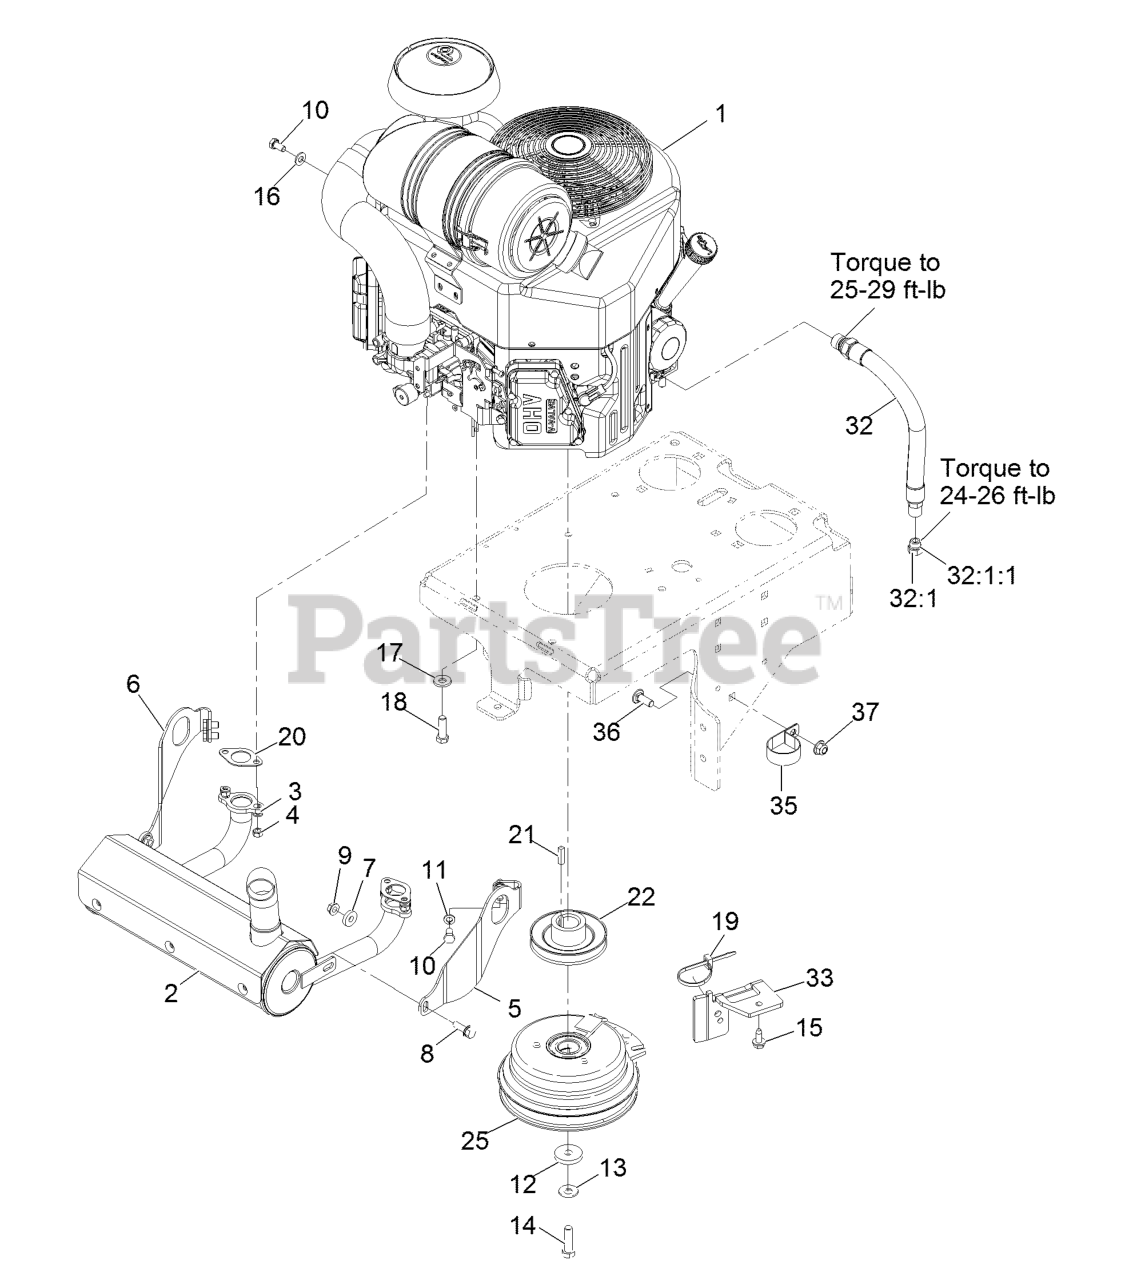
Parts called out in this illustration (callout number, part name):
2	MUFFLER, KAWASAKI, 22-26
3	WASHER-LOCK
5	BRACKET-MUFFLER MOUNT, LH
6	BRACKET-MUFFLER MOUNT, RH
8	SCREW-HHF
10	SCREW-HH
11	WASHER-LOCK
12	WASHER
13	WASHER-SPRING
14	SCREW-HH
15	Screw-HWH 5/16-18 X 3/4 Tf
16	WASHER-PLAIN
17	WASHER-BELLEVILLE
18	SCREW-HH
19	TIE-CABLE
20	GASKET-EXHAUST
25	CLUTCH-200 FT-LB, 1.125 B
32	ENGINE OIL DRAIN HOSE ASM
32:1	PLUG-HH
32:1:1	O-RING
33	BRACKET-ANCHOR, CLUTCH
35	CLAMP-R
36	SCREW-CARR
37	NUT-HF, NI
